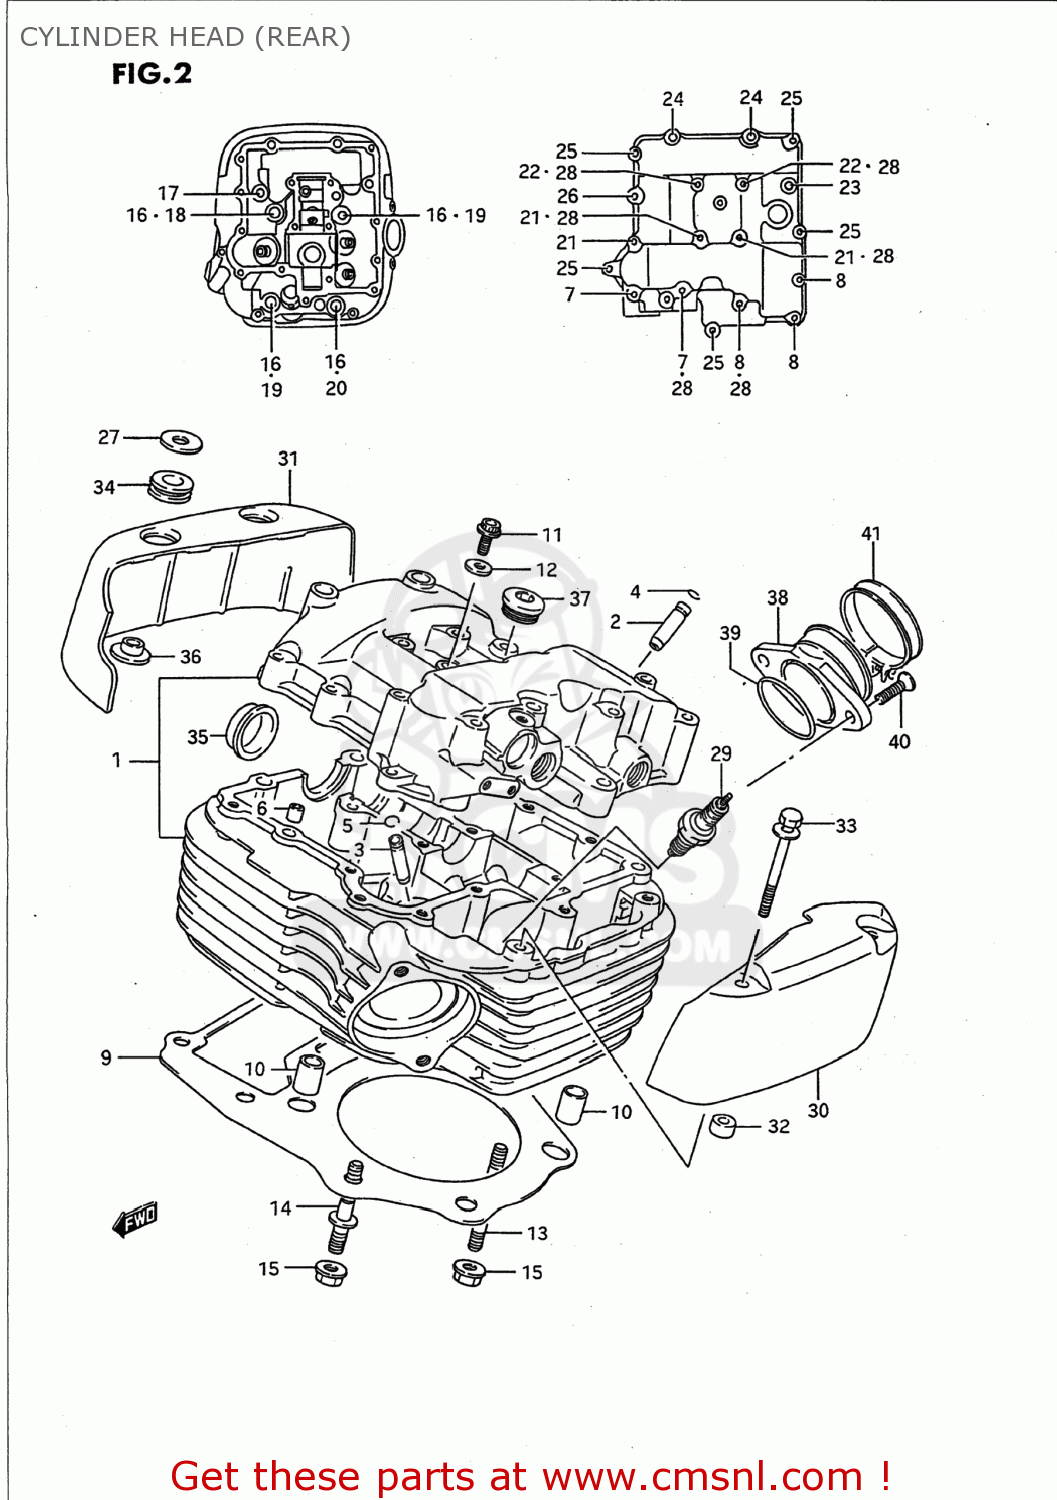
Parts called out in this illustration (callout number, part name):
1	HEAD ASSEMBLY,CYLINDER,REAR
2	GUIDE,INTAKE VALVE
3	GUIDE,INTAKE VALVE
4	RING,SNAP
5	RING,SNAP
6	PIN(6.2X8X11)
7	BOLT
8	BOLT(6X55)
9	GASKET,CYLINDER HEAD RR (NAS)
10	PIN
11	BOLT
12	GASKET(6.2X13X1.2) (NAS)
13	BOLT,STUD
14	BOLT,STUD
15	NUT
16	WASHER(10.5X22X2.3)
17	BOLT(8X57)
18	BOLT(10X180)
19	BOLT(10X190)
20	BOLT(10X215)
21	BOLT(6X50)
22	BOLT(6X45)
23	BOLT(8X130)
24	BOLT(8X268)
25	BOLT
26	BOLT
27	WASHER (8.2X24X1.6)
28	GASKET(5.8X13X1.2) (NAS)
29	SPARK PLUG DP8EA-9
30	CAP,CYLINDER HEAD COVER RL
31	CAP,CYLINDER HEAD COVER RR
32	CUSHION,R CAP
33	BOLT
34	CUSHION
35	PLUG(OD:30)
36	BUSH
37	PLUG,22X11
38	PIPE ASSEMBLY,INTAKE,REAR
39	O-RING (D:1.9 ID:40.7)
40	SCREW
41	CLAMP
